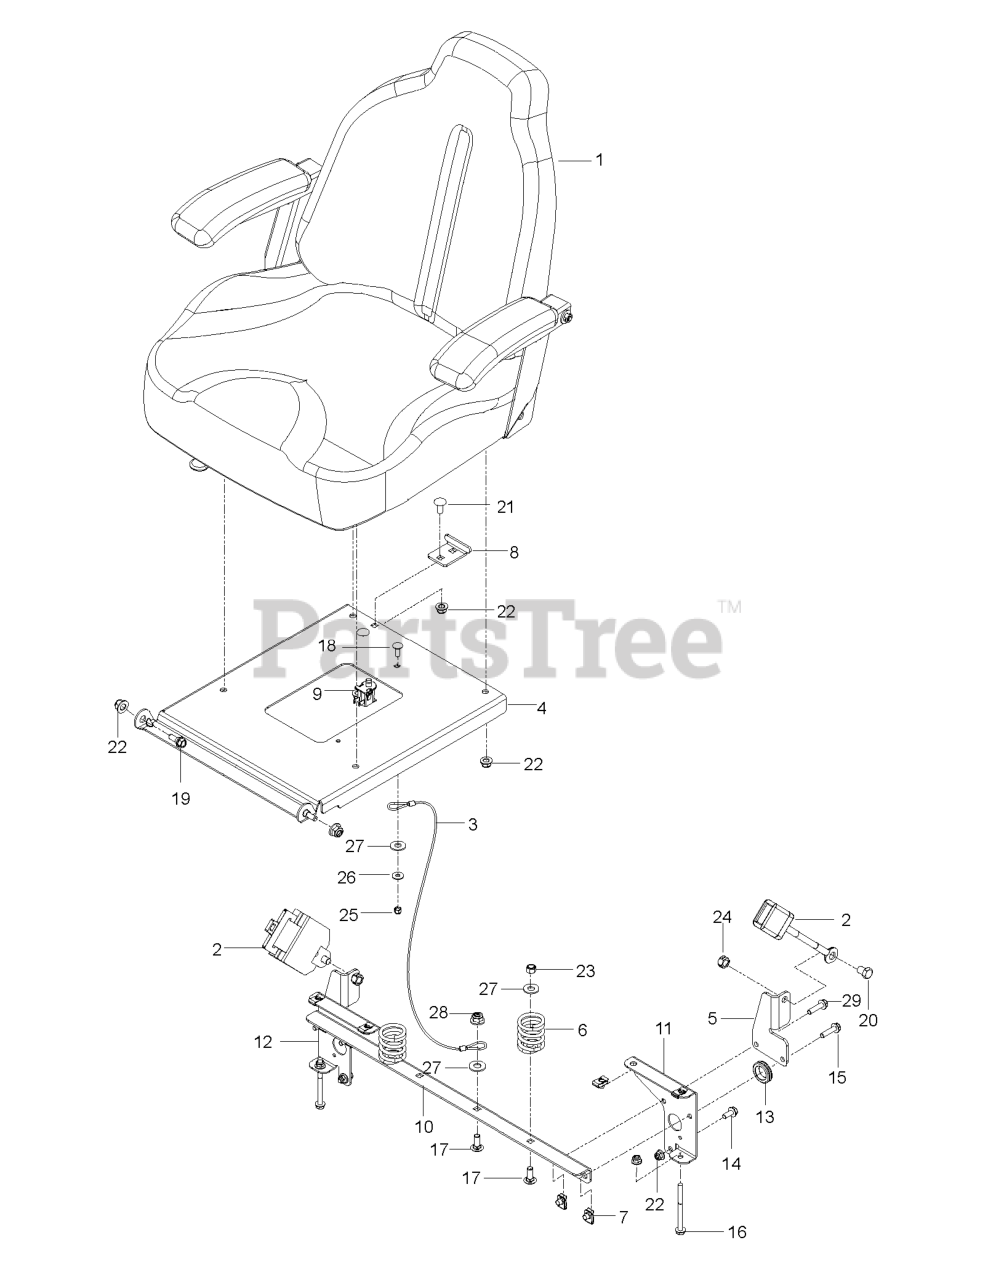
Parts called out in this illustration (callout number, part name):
1	SEAT.ASM.907.TRACK.W/O.BELT
2	SEAT BELT, RETRACTABLE
3	SEAT LANYARD
4	SUPPORT.SEAT.ORANGE
5	MOUNT.SEAT.BELT.BLACK
6	SPRING.COMPRESSION.SEAT.BLACK
7	U-CLIP 5/16-18 NUT RETAINER
8	STOP, SEAT - BLACK
9	SWITCH.INTRLCK.CLUTCH.
9	SEAT SWITCH
10	SUPPORT.SEAT. BLK
10	Brackets
11	SUPPORT.RT.BLK
11	SUPPORT.LT.BLK
12	SUPPORT.RT.BLK
12	SUPPORT.LT.BLK
13	RUBBER GROMMET
14	HHFS 5/16-18 X 3/4
15	Bolts
15	HHFS 5/16-18 X 1.25 TPBLT GD 5
16	BOLT.HEX.FLNG.5/16-18X3.75
17	RHSNB 3/8C X 1
17	Bolts
18	1/4-20X3/4 CARR BLT
18	BOLT CUP HEAD SQUARE NECK BOLT
19	SB 5/16-18 HEX HD GD5, BLK ZN
20	HCS 7/16-20 X .75 GD 5
20	SCREW 7/16-20 X 1 HHB GR5
21	RHSNB 5/16-18 X 3/4 GR5 BLK ZN
22	NUT.71038.31-18.HEX.NYLOCK
22	NUT HEXAGON FLANGE 5/16-18 ST
22	5/16-18 NYLOC FLANGE NUT
23	GSPW Nuts
23	NUT 3/8-16 NYLOC
23	NUT 3/8-16 HEX FLG NYLOC ZD
24	NUT HEX 7/16F LOCK RP
25	NUT.1/4-20.HEX.NYLOC.ZD
25	NUT HEXAGON 1/4-20 ST ZPB
26	Washers
26	WASHER PM
27	GSPW Washers
27	RP WASHER 3/8 FLAT
28	NUT 3/8-16 HEX FLG NYLOC ZD
28	NUT 3/8-16 NYLOC
29	Bolts
